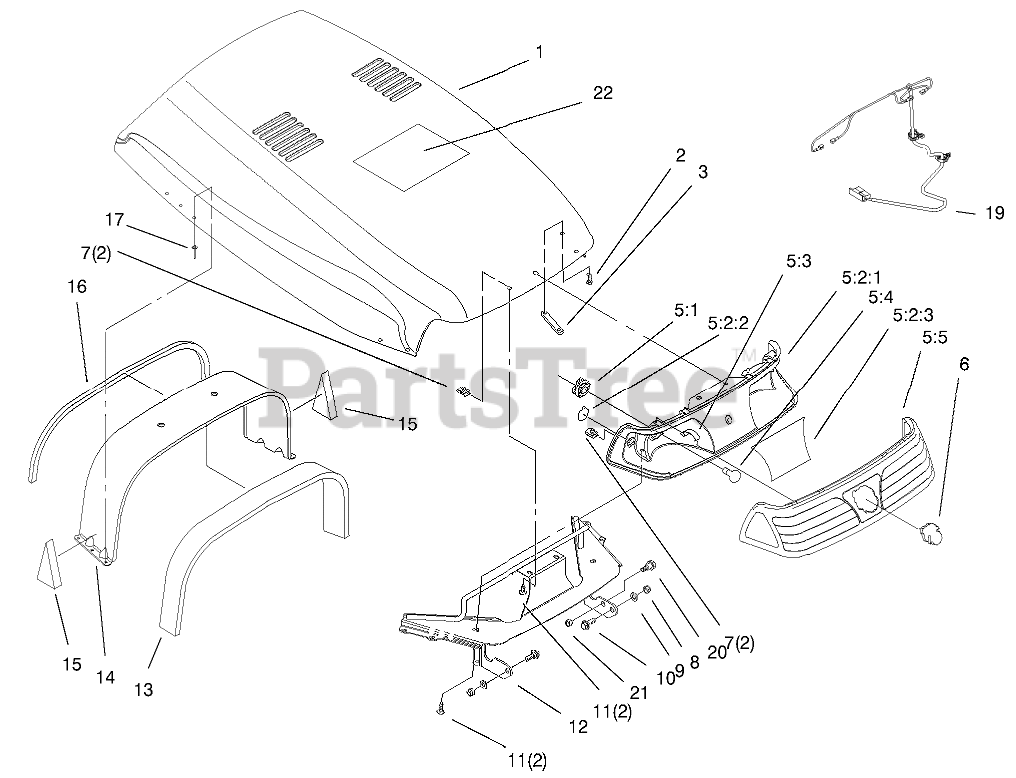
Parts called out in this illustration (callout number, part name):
1	HOOD ASM
2	SCREW
3	PLATE-NUT
5:1	SEALED SOCKET ASM
5:2:1	REFLECTOR-HEADLIGHT
5:2:2	DECAL-SIDELIGHT
5:2:3	DECAL-REFLECTOR, HEADLIGHT
5:3	CLIP-RETAINER
5:4	BULB
5:5	LENS-HEADLIGHT
6	EMBLEM
8	NUT-LOCK, NI
9	WASHER-PLAIN
10	SCREW-SHOULDER
11	SCREW-HH
12	BULKHEAD-FRONT
13	SEAL-FOAM, REAR
14	Bulkhead-Rear
15	FOAM-BULKHEAD, LOWER
16	FOAM-TAPE
17	RIVET-POP
19	HARNESS-WIRE, LIGHTS
20	BOLT-SHOULDER
21	NUT-LOCK, NI
22	Decal-Services 5xi (only on: 73547)
